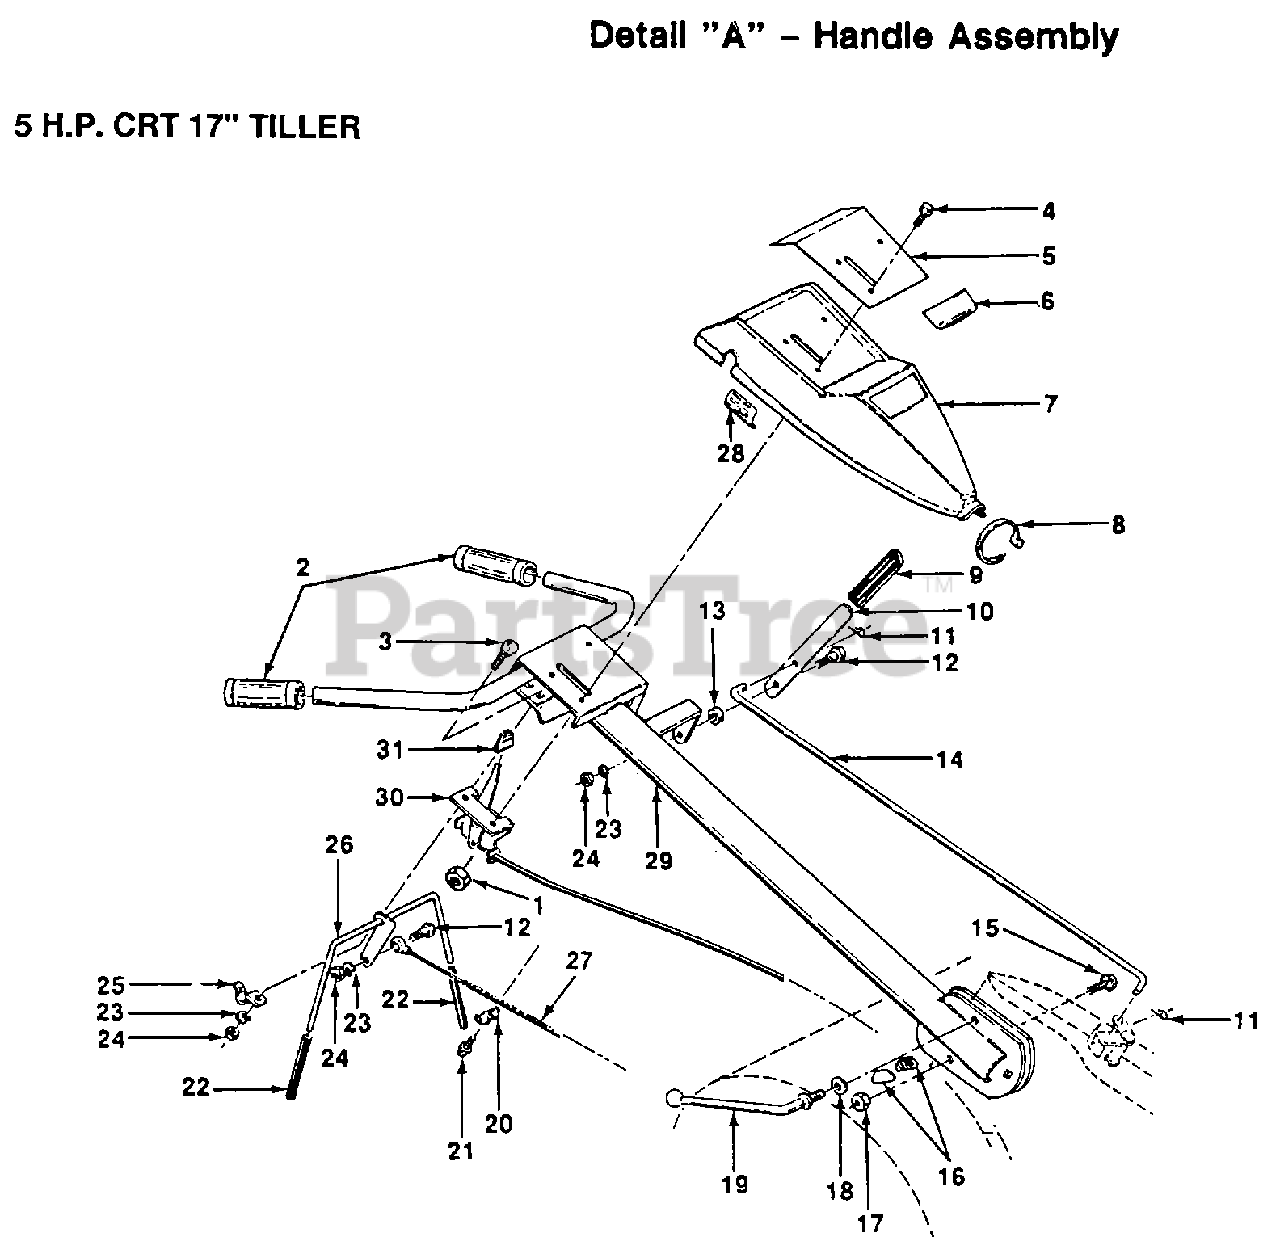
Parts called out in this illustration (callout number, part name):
3	BOLT
4	SCREW
7	PANEL CONTROL
8	TIE CABLE CRT
9	GRIP T
10	SHIFT HANDLE CRT
11	RETAINER M
12	SHOULDER BOLT ST
13	GROMMET CRT
14	SHIFT ROD CRT
15	BOLT D
16	LOCK CRT
18	WASHER CRT
19	LEVER LOCK CRT
20	CONDIUT CLIP T
22	GRIP BAR CRT
23	LOCKWASHER
25	"ROD, FRT. PARAL T"
26	"ASSY CONTROL, BAR"
27	CABLE.CLUTCH.CRT
28	DECAL TI
30	THROTTLE CRT
31	KNOB CRT
